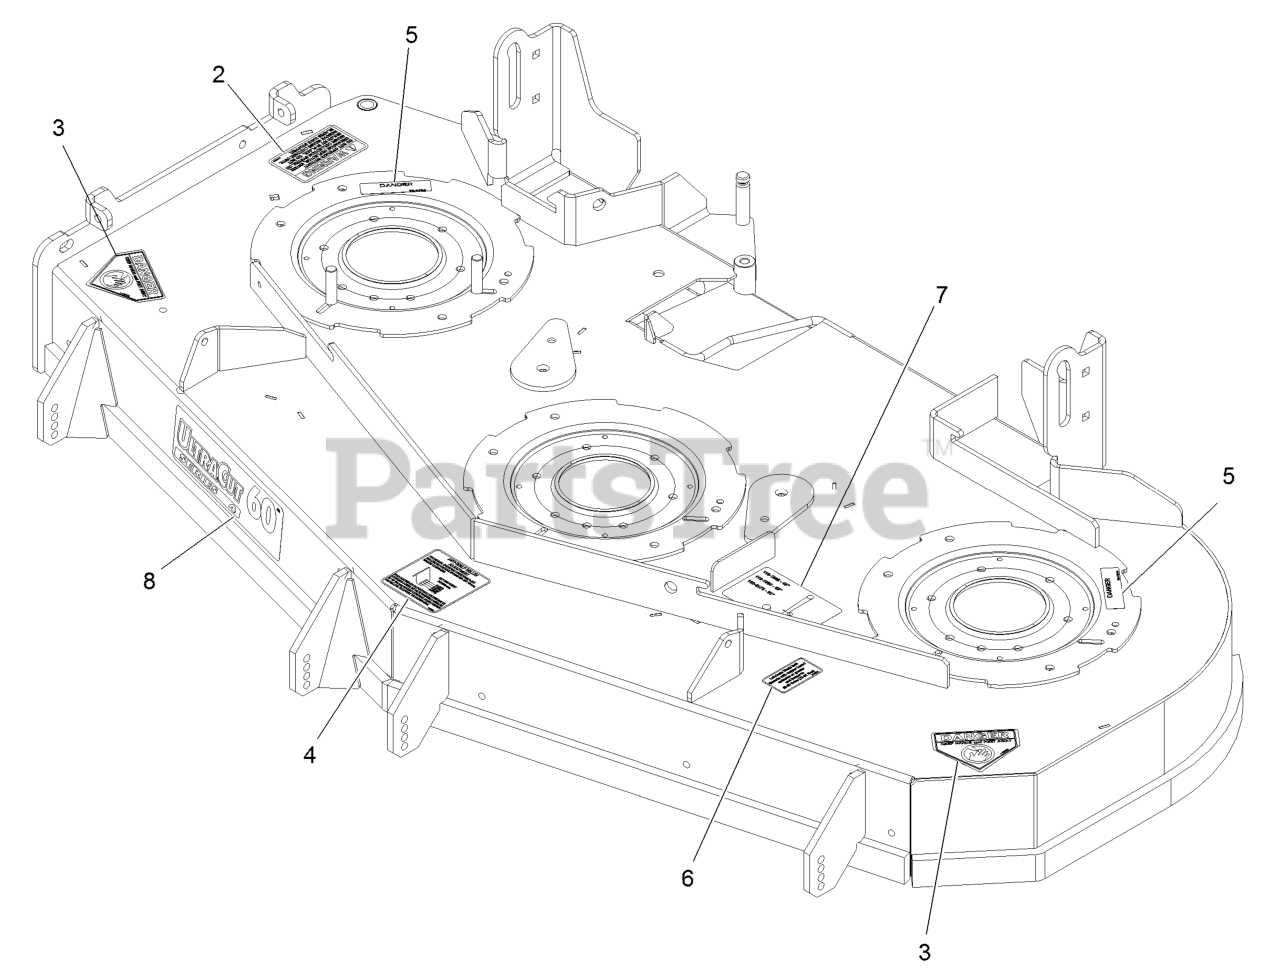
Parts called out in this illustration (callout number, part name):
2	DECAL-WARNING, DISCHARGE
3	DECAL-DANGER
4	DECAL,ANTISCALP
5	DECAL-COVER, MISSING
6	DECAL,BOLT TORQUE
7	DECAL-BELT ROUTING
8	DECAL,ULTRACUT 60 SERIES
